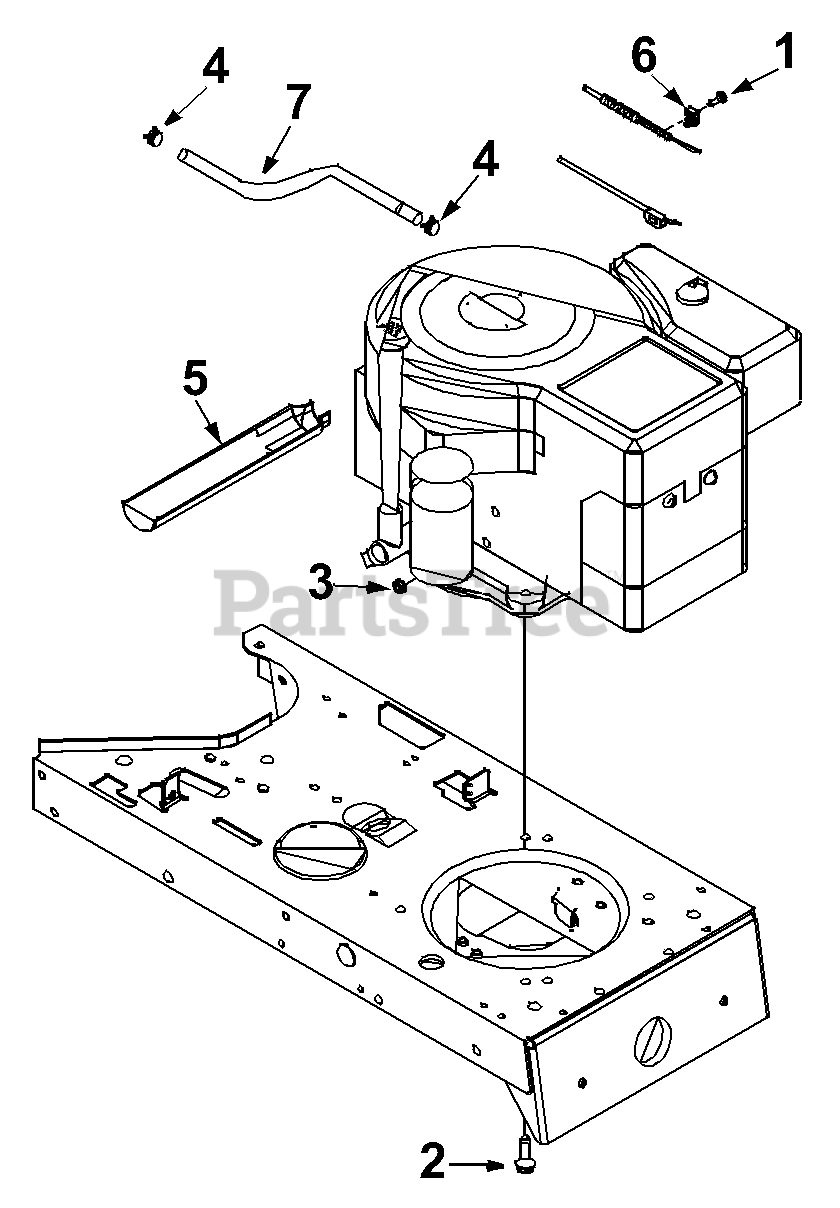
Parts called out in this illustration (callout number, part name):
1	Screw
2	Hex Wash. Hd. TT-Scr. 3.8-16 x 1.25"
3	Hex Sems Nut 1/4-20 Thd.
4	Hose Clamp
5	Oil Drain Sleeve
6	Casing Clamp
7	Fuel Line
